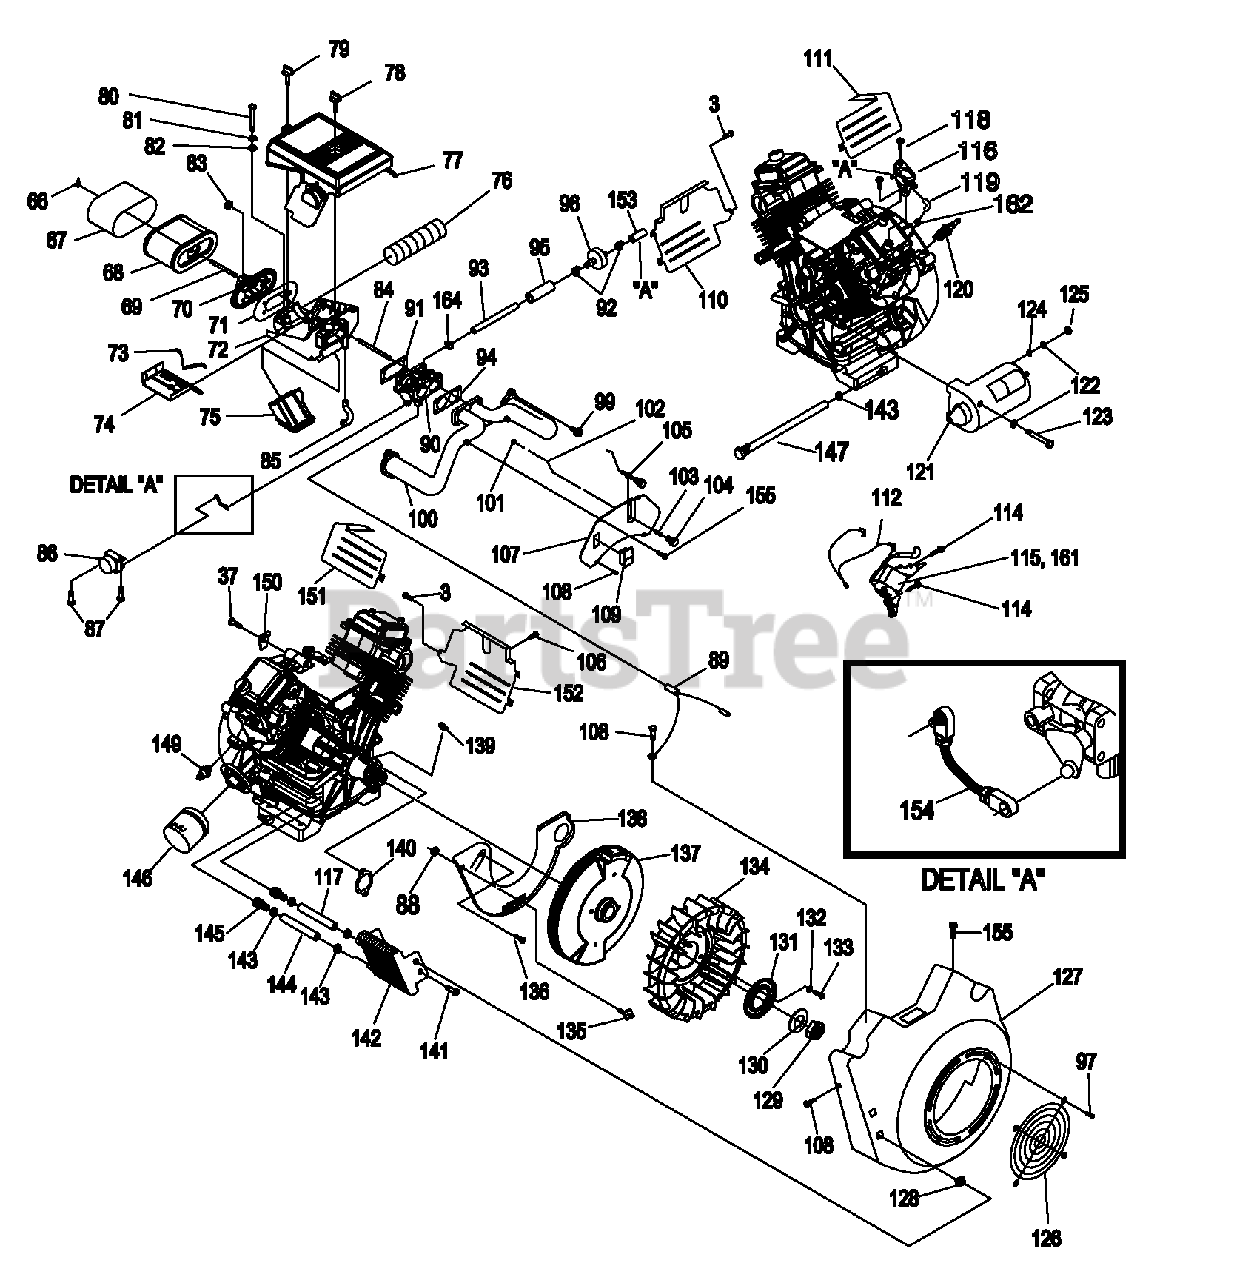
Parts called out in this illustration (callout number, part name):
66	WINGNUT, AIRBOX
67	PRECLEANER, AIR
68	ELEMENT, AIR CLEANER
69	STUD M6-1.0 X 73
70	ADAPTOR, SPIT BACK
71	GASKET, SPITBACK
72	BASE, AIRBOX
73	SPRING, WINTER/SUMMER VALVE
74	VALVE, SUMMER / WINTER
75	SNORKEL, AIR INTAKE
76	TUBE, HEAT RISER 50.8 I.D.
77	COVER, AIRBOX
78	KNOB, AIRBOX 17mm
79	KNOB, AIRBOX 95MM
80	SCREW HHC M6-1.0 X 35
81	WASHER LOCK M6-1/4
82	WASHER FLAT 1/4
83	NUT, HEX FLANGE WHIZ M6-1.0
84	STUD, METRIC
85	HOSE, BREATHER
86	ASSY,CONTROLLER, GTH990 PORTABLE
87	SCREW HHTT M5-0.8 X 10
88	NUT, HEX LOCK M5-0.8 ZINC
89	ASSEMBLY, WIRE
90	CARBURETOR, H990 W/BALL STUD
91	GASKET, CARB TO SPACER (GT-990)
92	CLAMP HOSE BAND 1/4
93	HOSE 1/4 ID SAE 30R7 GREENBAR 9" PRE-CUT
94	GASKET, MANIFOLD TO CARBURETOR
95	SLEEVING, FLEXO HW 3/4 3"
96	FILTER, FUEL
97	SCREW, HHTT M6-1 x 10 LONG
98	NUT, HEX LOCK M5-0.8 ZINC
99	SCREW, SHC M8-1.25 x 25 LG SEMS
100	MANIFOLD, INTAKE
101	NUT HEX M3-0.5
102	ROD, SUMMER / WINTER VALVE
103	BUSHING, MINI CONTROL PANEL
104	KNOB, CONTROL SUMMER / WINTER, BLACK
105	CHOKE ASSEMBLY
106	SCREW TAPTITE M5-0.8 X 8 ZP
107	PANEL, CONTROL FACE PLATE
108	SCREW TAPTITE M6-1.0X 12 CLEAR ZINC
109	SWITCH ROCKER
110	WRAPPER, LOWER CYLINDER 2
111	WRAPPER, UPPER CYLINDER 2
112	ASSEMBLY, GROUND WIRE
114	SCREW TAPTITE M6-1.0 X 20 ZINC
115	ASSY, IGN COIL W/DIODE NO ADV
116	PUMP, IMPULSE
117	HOSE 3/8" 300PSI 6.5" LG OIL
118	SCREW, HHFCS M6-1.0 X 16 G8.8
119	ELBOW, RUBBER 90 DEG. GASOLINE
120	SPARKPLUG, CHAMPION RC14YC
121	STARTER MOTOR GEAR REDUCED
122	WASHER LOCK M8-5/16
123	SCREW HHC M8-1.25 X 85 G8.8
124	WASHER, FLAT M8
125	NUT, HEX M8-1.25 YELLOW ZINC
126	GUARD,FAN
127	HOUSING, BLOWER GAS COOLER
128	NUT, GROMMET 1/4 PLUG
129	NUT,HEX M24
130	WASHER, M24
131	PLATE, FAN
132	WASHER SHAKEPROOF INT M8 SS
133	SCREW HHC M8-1.25 X 12 G8.8
134	FAN, NYLON
135	ASSY,GROUND WIRE CONNECTOR
136	SCREW TAPTITE M6-1X10 YELLOW CHROME
137	FLYWHEEL ASSEMBLY
138	PLATE, BACKING GT990 W/OIL COOL ZINC
139	KEY, WOODRFF 4 X 19D
140	GASKET, MANIFOLD / PORT
141	PLASTITE,1/4-15 X 3/4
142	COOLER, OIL
143	CLAMP, HOSE OETIKER STEPLESS 18.5mm
144	HOSE 3/8" 300PSI 6.5" LG OIL
145	BARBED STR 1/4NPT X 3/8
146	OIL FILTER, 90mm w/LOGO
147	ASSEMBLY, OIL DRAIN HOSE
149	SWITCH, OIL PRESS
150	BRACKET, AIRBOX SUPPORT
151	WRAPPER, UPPER CYLINDER 1
152	WRAPPER, LOWER CYLINDER 1
153	HOSE, 1/4" SAE 30R7 GREENBAR
154	ASSY, ROD, GOV. STEPPER MOTOR
155	SCREW HHHC M6-1.0 X12
157	NUT, LOCK HEX M3-0.5 (GT-990)
160	SCREW HHFC M6-1.0 X 10mm
161	ASSY, IGN COIL W/DIODE NO ADV
162	CLAMP, HOSE BAND GREEN
163	BALL STUD, 10mm
164	CLAMP, HOSE WORM GEAR
